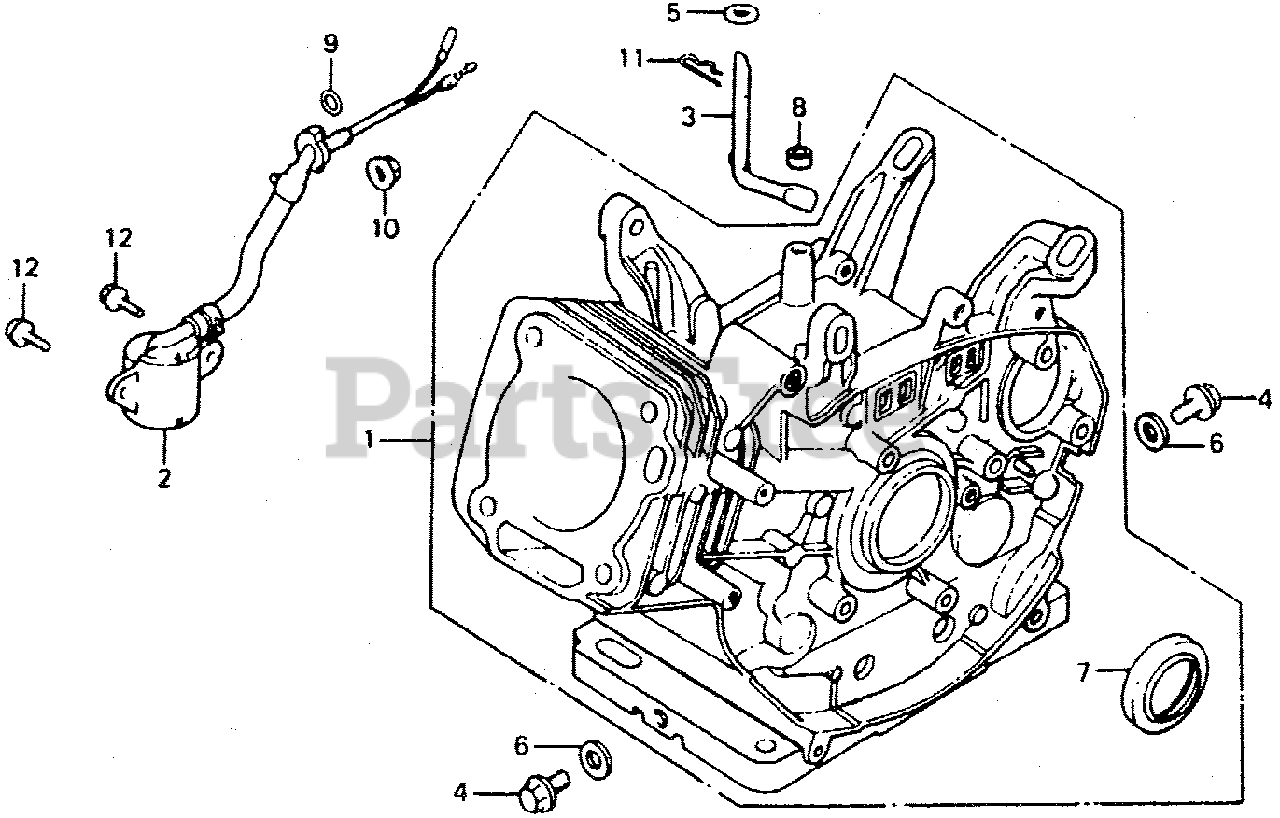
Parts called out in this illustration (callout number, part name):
1	CYLINDER ASSY.
2	SWITCH ASSY., OIL LEVEL
3	SHAFT, GOVERNOR ARM
4	BOLT, DRAIN PLUG
5	WASHER (8.2X17X0.8)
6	WASHER, DRAIN PLUG (12MM)
7	OIL SEAL (30X46X8)
8	OIL SEAL (8X14X5)
9	O-RING (13.5X1.5) (ARAI)
10	NUT, FLANGE (10MM)
11	PIN, LOCK (8MM)
12	BOLT, FLANGE (6X12)
NI	GOVERNOR KIT (STD)
